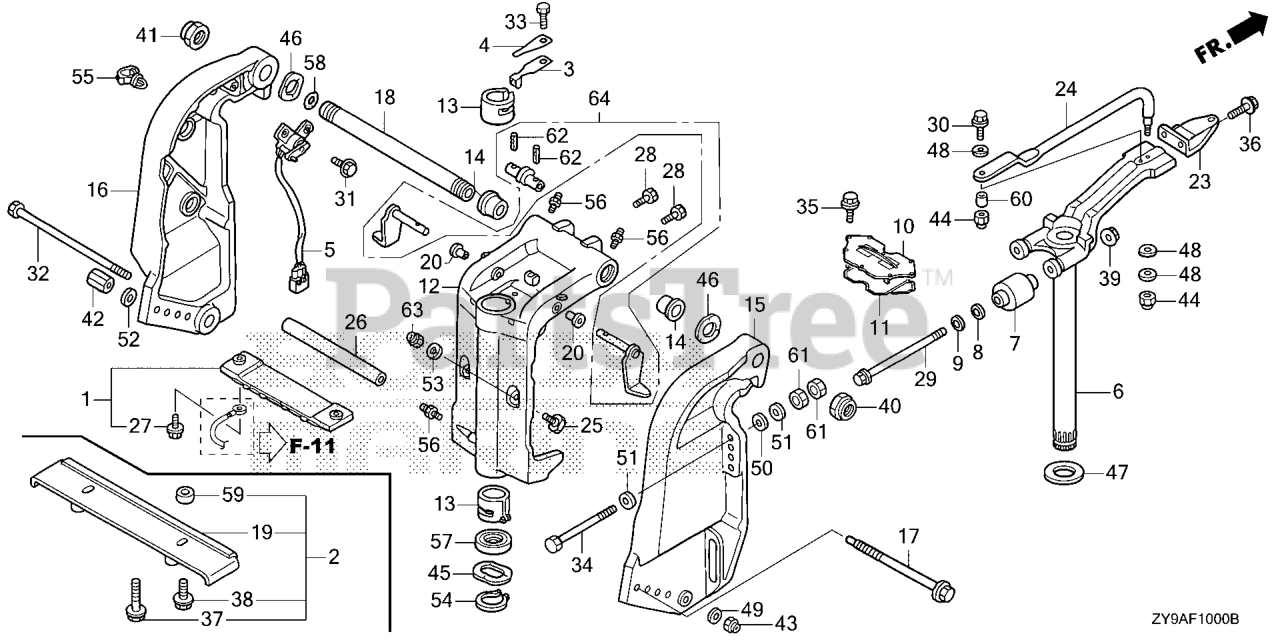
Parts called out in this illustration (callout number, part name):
1	METAL KIT, ANODE Use from Frame SN 4800343.
2	PLATE KIT, SPLASH
3	SPRING, CLICK
4	SPRING, CLICK ASSIST
5	SENSOR ASSY., TRIM ANGLE
6	FRAME, MOUNTING
7	MOUNT, RUBBER (UPPER)
8	RUBBER, MOUNT STOPPER (UPPER)
9	STOPPER, MOUNT (UPPER)
10	COVER, MOUNT (UPPER)
11	SEAL, MOUNT COVER (UPPER)
12	CASE, SWIVEL *NHB14M* (AQUA MARINE SILVER METALLIC)
13	LINER, SWIVEL CASE
14	BUSH, SWIVEL CASE
15	BRACKET, R. STERN *NHB14M* (AQUA MARINE SILVER METALLIC)
16	BRACKET, L. STERN *NHB14M* (AQUA MARINE SILVER METALLIC)
17	ROD, ADJUSTING
18	SHAFT, TILTING
19	PLATE, SPLASH
20	BUSH, TILT ARM
21	BRACKET, TILTING
22	STOPPER, TILT
23	PLATE, STEERING
24	ROD, STEERING
25	RECEIVER, THRUST
26	COLLAR, CYLINDER (LOWER)
27	BOLT, FLANGE (6X23) Use from Frame SN 4800343.
28	BOLT (1/4-28UNF)
29	BOLT, HEX. (12X186)
30	BOLT (3/8-24UNF)
31	BOLT, FLANGE (6X20) (ENGINE NO.)
32	BOLT, HEX. (10X235)
33	BOLT, HEX. (6X14)
34	BOLT, HEX. (12X119)
35	BOLT, FLANGE (8X25)
36	BOLT, FLANGE (10X25)
37	BOLT, FLANGE (6X25) (SUS-D)
38	BOLT, FLANGE (6X16) (SUS)
39	NUT, FLANGE (12MM)
40	NUT, SELF-LOCK (7/8-14UNF)
41	NUT, SELF-LOCK (M25X2.0)
42	NUT, ADJUSTER ROD
43	NUT, SELF-LOCK (10MM)
43	NUT, FLANGE (10MM)
44	NUT, SELF-LOCK (3/8-24UNF)
45	WASHER, WAVE (40MM)
46	WASHER, WAVE (26MM)
47	WASHER, THRUST (34MM)
48	WASHER (10MM)
49	WASHER, PLAIN (10MM)
50	WASHER, PLAIN (12MM)
51	WASHER, PLAIN (12MM)
52	WASHER, PLAIN (12MM)
53	WASHER, PLAIN (10MM)
54	CIRCLIP (OUTER) (39MM)
55	CLIP, WIRE HARNESS
56	NIPPLE, GREASE
57	OIL SEAL (39.5X52X6) (ARAI)
58	O-RING (15.54X2.26)
59	COLLAR, SPLASH PLATE
60	COLLAR, STEERING ROD
61	NUT, HEX. (12MM)
62	PIN, SPRING (2.5X20)
63	NUT, SELF-LOCK (10MM)
63	NUT, FLANGE (10MM)
64	STOPPER KIT, TILT
